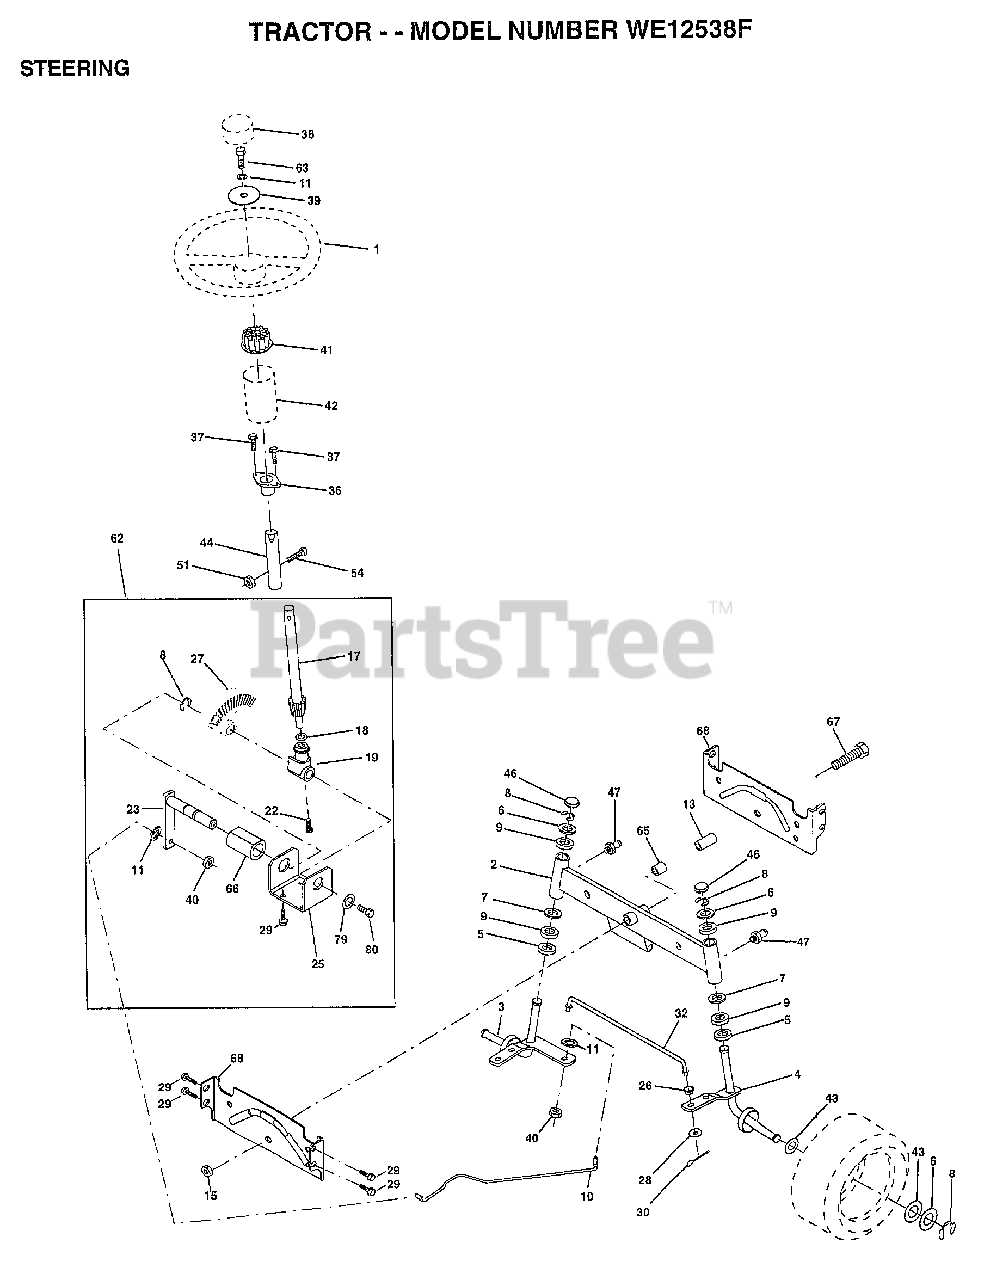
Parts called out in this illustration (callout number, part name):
1	WHEEL STR AYP BLK
2	AXLE ASM
3	SPINDLE.ASM.LH
4	"SPINDLE ASM,RH"
5	WASHER .T
6	WASHER
7	WASHER
8	RING
9	COL. SRTG. BEAR.
10	DRAGLINK-STAMPED
11	LOCKWASHER
13	BEARING AXLE
15	"NUT-LOC,FLANGE LT"
17	SHAFT ASM STEERIN
18	THRUST WASHER
19	SUPPORT.SHAFT.STEER
22	SCREW.HX.WSH.HD
23	SHAFT.ASM.PITMAN
25	BRKT-STEERING
26	BUSHING.DRAGLINK
27	GEAR SECTOR
28	WASHER
29	SCREW
30	COTTER PIN
32	TIE ROD
36	BUSHING.STEERING
37	"SCREW-TT,10-32 FL"
38	CAP STEER AYP
39	WASHER T
40	GRIPCO NUT
41	ADAPTER LT
42	BOOT.STEER.PL
43	WASHER
44	EXT SHAFT STEERIN
46	CAP
47	ZERK M
51	NUT
54	BOLT
62	KIT.STEER.ASM
63	BOLT
65	SPACER AXLE
66	"BEARING-ARM,PITMA"
67	BOLT
68	BRACE AXLE
79	WASHER
80	BOLT.HX.NYLON3/8-16X3/
